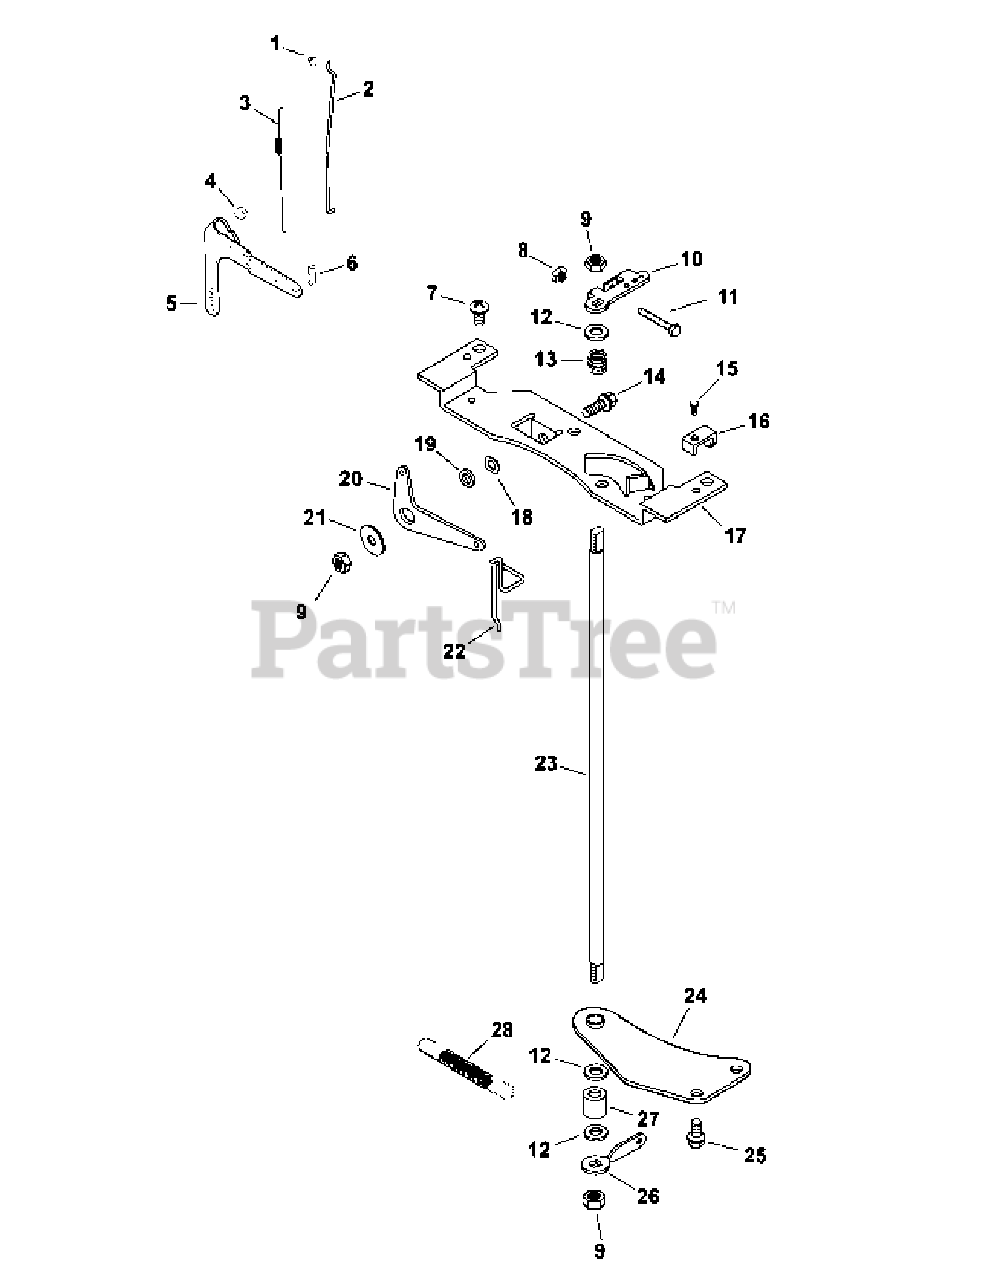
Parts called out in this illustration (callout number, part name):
1	Linkage Retaining Bushing
2	Throttle Linkage
3	Linkage Spring
4	Flange Nut, M6 x 1.0
5	Governor Lever
6	Throttle Linkage Bushing
7	Screw, 11-16 X 3/4
8	Nut, M4 x 0.7
9	Lock Nut, M6 x 1.0
10	Throttle Control Lever
11	Cap Screw, M4 x .7 X 30
12	Flat Washer, 1/4
13	Throttle Shaft Spring
14	Flange Screw, M6 x 1.0 x 16
15	Flange Screw, M5 x 0.8 x 16
16	Cable Clamp
17	Control Bracket
18	Spring Washer, 3/8
21	Flat Washer, 1/4
22	Choke Linkage
23	Throttle Shaft
24	Throttle Shaft Bracket
25	Flange Screw, M6 x 1.0 x 16
26	Throttle Control Lever
28	Governor Spring (Black)
